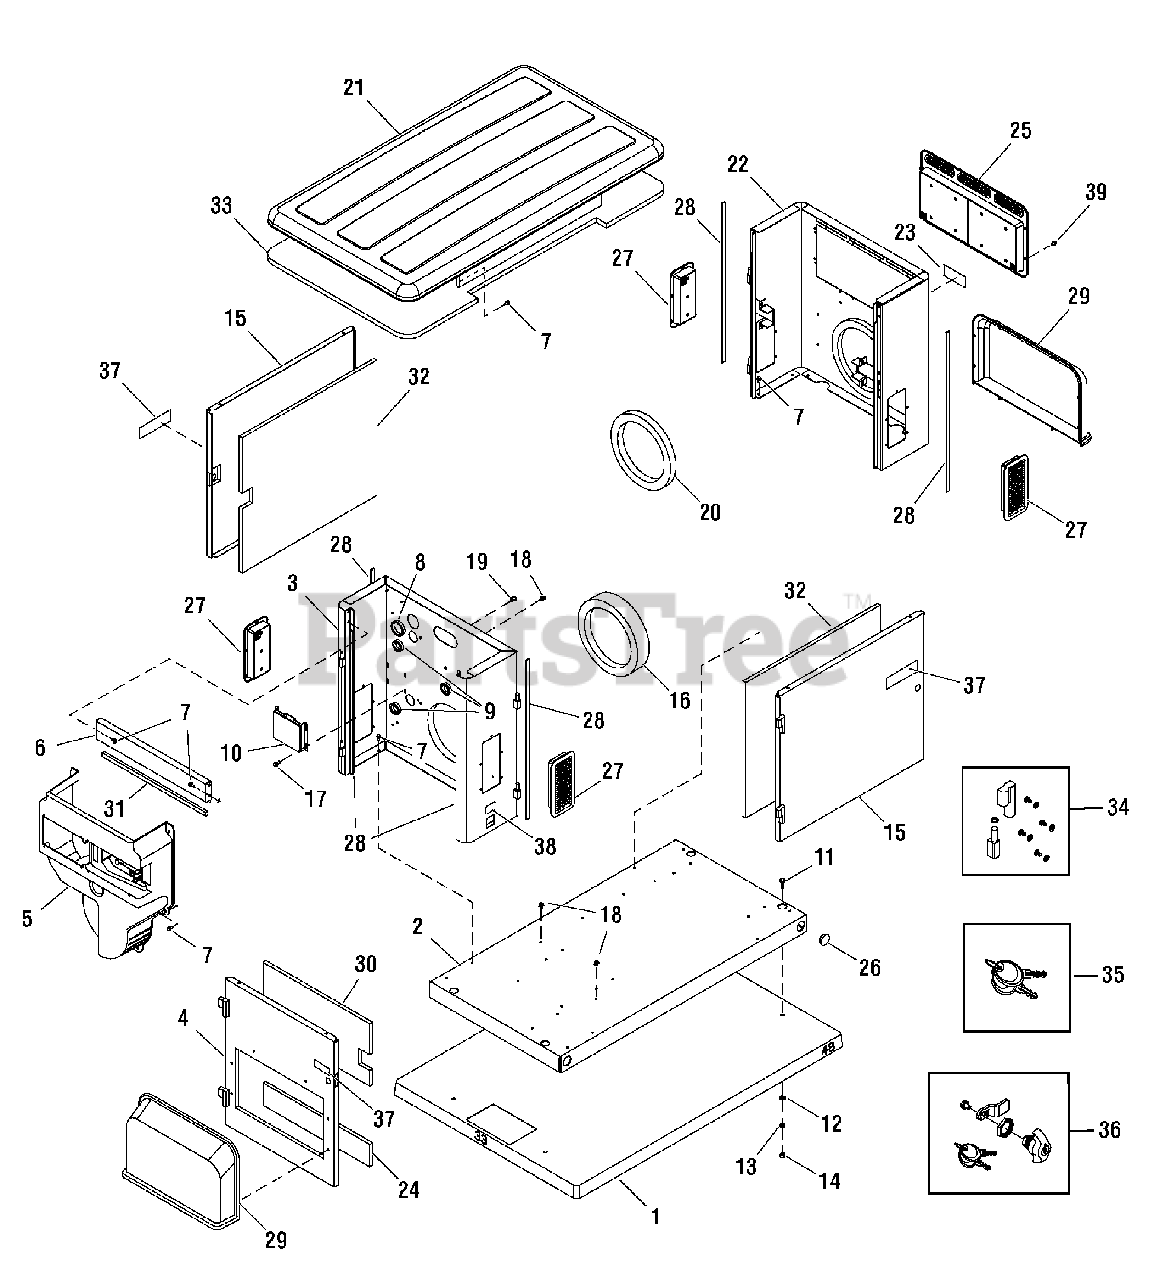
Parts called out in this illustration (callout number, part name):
2	BASE
3	BULKHEAD ASSEMBLY, Engine
6	SUPPORT RAIL ASSEMBLY
7	BOLT
10	REGULATOR, Voltage, Full Wave
11	* CAPSCREW, Hex Head, 3/8-16 x 1
12	* WASHER, Flat, 3/8-M10
13	* WASHER, Lock, 3/8
14	* NUT, 3/8-16
16	SEAL, Foam
20	SEAL, Foam
22	BULKHEAD ASSEMBLY, Alternator
24	COVER, Air Intake
29	COVER, Air Intake
